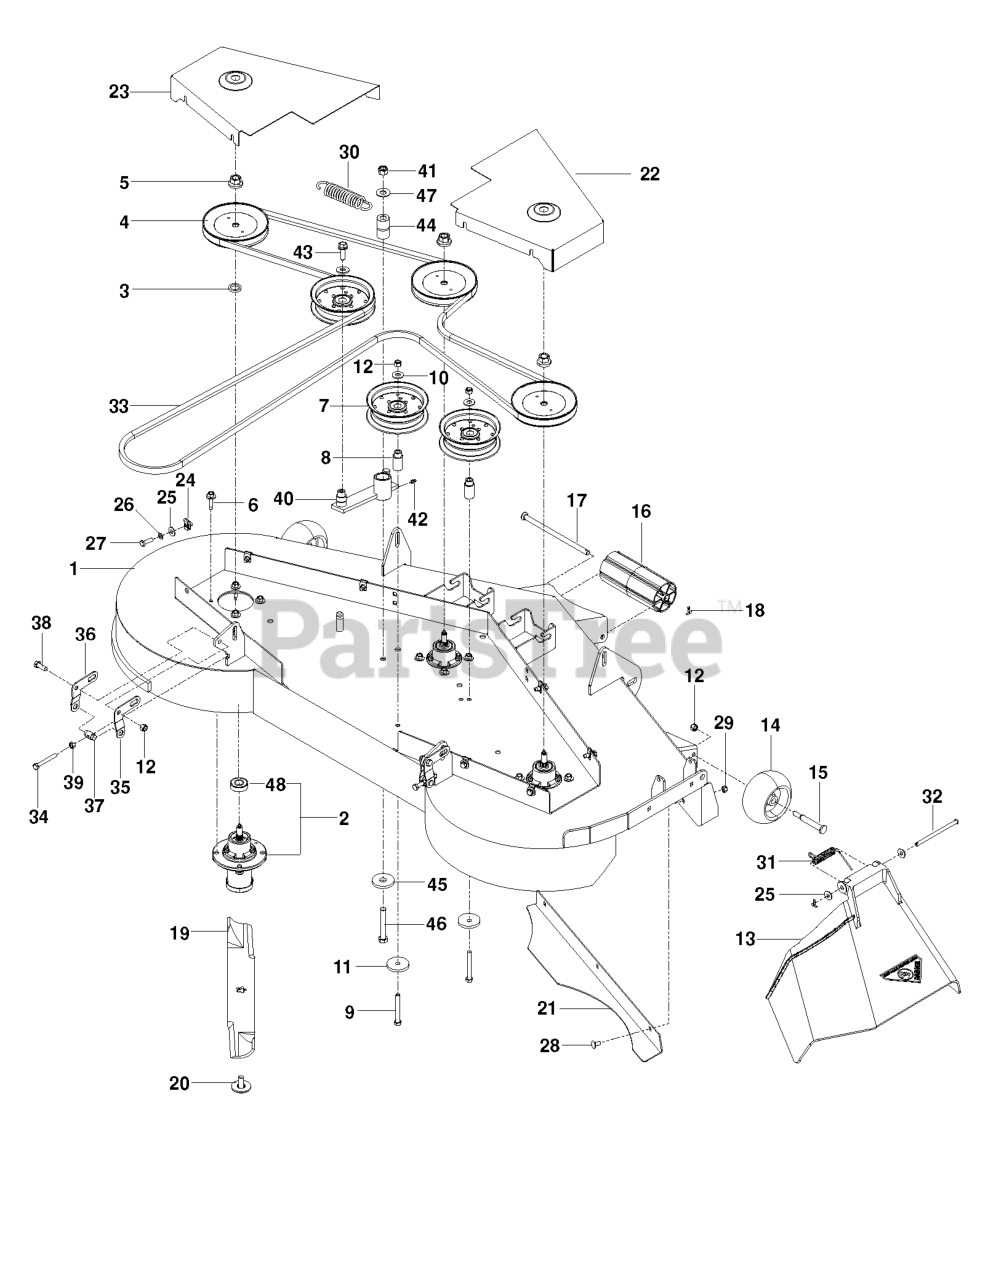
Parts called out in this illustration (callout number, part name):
1	DECK.SVC.W/DECALS.61".EZ.ORANG
2	MANDREL.DECK.ASSEMBLY
3	WASHER-SPACER
5	LOCKNUT - 9/16
6	WASHER HEAD SCREW
7	PULLEY, IDLER
8	IDLER BUSHING
9	HCS 3/8C X 3
10	WASHER 3/8 FLAT
11	SUPPORT PLATE
12	NUT 3/8-16 NYLOC
13	DISCHARGE CHUTE 61"
14	GAUGE WHEEL
15	SHOULDER BOLT 1/2X2-5/8 ZD SPE
16	NOSE ROLLER 48"
17	NOSE ROLLER ROD
18	RP_COTTER PIN 1/8 X 3/4
19	BLADE, 21"
20	BLADE BOLT ASSY-7/16" TB REPL
21	CONFINEMENT PLATE 61
22	BELT SHIELD, RH ORANGE
23	BELT.SHIELD.LH.ORANGE
24	U-CLIP 5/16-18 NUT RETAINER
25	WASHER 5/16 FLAT
26	WASHER.LOCK.HVY.HLCL.SPR.5/16
27	HCS 5/16C X 1
28	CARRIAGE BOLT 5/16C X 5/8"
29	NUT 5/16 NYLOC
31	SPRING - TORSION
32	PIN-CLEVIS 5/16 DIA X 5.19 ZD
33	BELT, DECK
34	HCS 5/16-18 X 2 1/2 TPBLT
35	PITCH, ADJUST, RT
36	PITCH, ADJUST, LT
37	TRUNION, PITCH
38	HCS 3/8-16X1.GRD.5.ZD
39	NUT 5/16C HEX
41	NUT 1/2-13 HEX NYLOC ZD
42	ZERK
43	4CS 3/8C X 1 SERRATED HEAD
44	PIVOT BUSHING
45	WASHER, SUPPORT
46	HCS 1/2C X 3 1/4
47	WASHER 1/2 FLAT
48	BEARING, BALL
